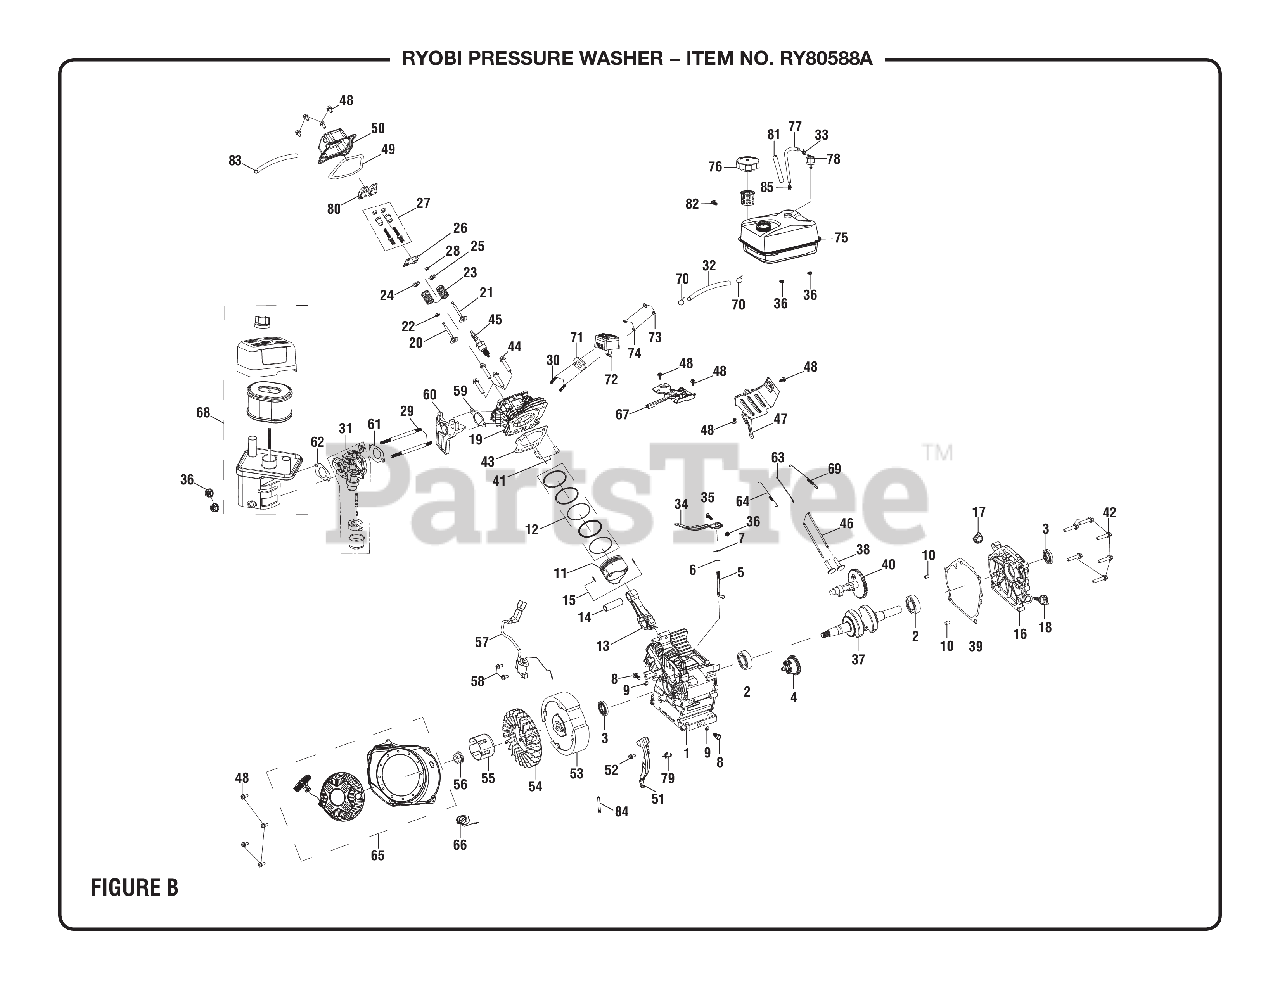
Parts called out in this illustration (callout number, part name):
2	Ball Bearing
4	Governor Assembly
5	Governor Arm Shaft
6	Governor Arm Shaft Washer
8	Drain Plug Bolt
9	Drain Plug Washer
10	Casecover Dowel Pin
12	Scraper Ring Set Piston
13	Connecting Rod Assembly
15	Piston Clip
16	Crankcase Cover Assembly
19	Cylinder Head
20	Intake Valve
21	Exhaust Valve
22	Intake Valve Retainer
23	Valve Spring
24	Intake Valve Spring Seat
25	Exhaust Valve Spring Seat
26	Push Rod Guide Plate
27	Rocker Arm Bolts
31	Carburetor Assembly
33	Fuel Line Clip
34	Governor Arm
35	Governor Arm Bolt
37	Crankshaft Assembly
38	Valve Lifter
39	Casecover Packing
40	Camshaft Assembly
42	Bolt (M8 x 30 mm)
43	Cylinder Head Gasket
44	Bolt (M8 x 60 mm)
48	Bolt (M6 x 12 mm)
49	Headcover Packing
50	Cylinder Head Cover Comp
51	Wind Shiel Comp
52	Bolt (M6 x 20 mm)
53	Flywheel Assembly
54	Recoil Starter Fan
55	Starter Pulley
57	Ignition Coil Assembly
58	Bolt (M6 x 25 mm)
59	Intake Packing
60	Carburetor Insulator
61	Carburetor Packing
62	Empty Filter Gasket
63	Governor Rod
64	Throttle Return Spring
65	Recoil Starter Assembly
66	Switch Assembly
67	Upper Shroud Assembly
68	Air Cleaner Assembly
69	Governor Spring
70	Fuel Line Clip
71	Exhaust Packing
72	Muffler Comp
74	Spring Washer
75	Fuel Tank Assembly
77	Connecting Pipe
78	Manual Choke Assembly
81	Ventilation Tube Protector
82	Bolt (M6 x 28 mm)
83	Breather Tube
84	Wire Harness Clip
85	Fuel Line Clip (95)
